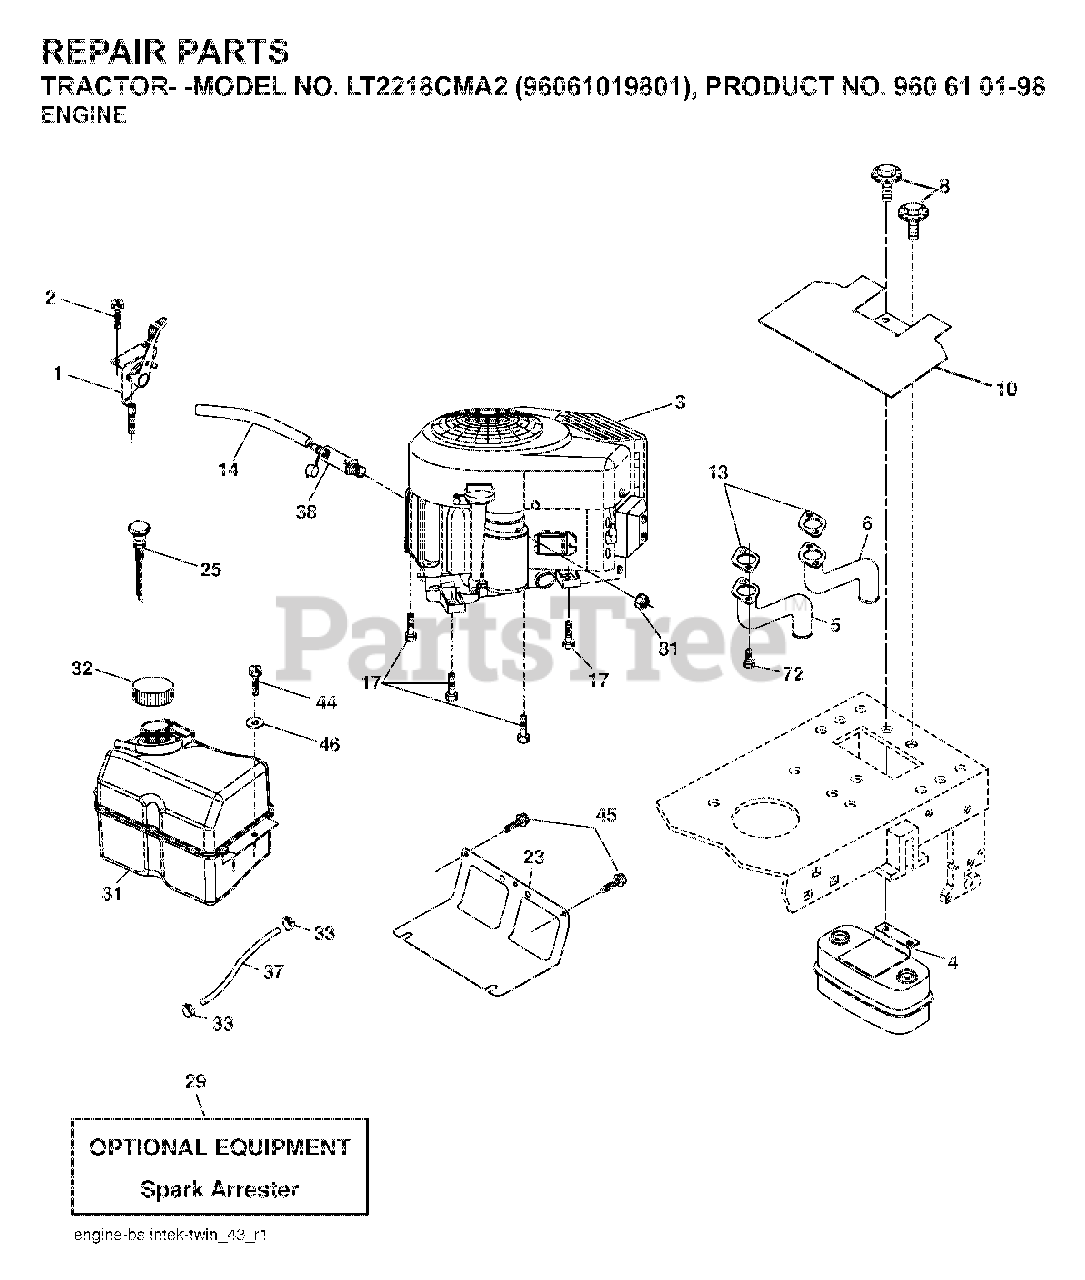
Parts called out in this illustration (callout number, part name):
1	THROTTLE CABLE
2	SCREW
4	MUFFLER.TWIN.CYL.LOW.TONE
5	EXHAUST TUBE RH
6	TUBE MANIFOLD LH
8	BOLT, 5/16-18 X 1 3/4
10	RP SHIELD HEAT MUFFLER
13	GASKET.MUFFLER
14	TUBE, DRAIN OIL ASM.
17	SCREW.3/8-16
23	SHEILD.BROWNING.DBR.GUARD
25	CONTROL CHOKE
29	ARRESTER SPARK (OPTIONAL)
31	TANK FUEL
32	FUEL CAP
33	HOSE CLAMP
37	LINE.FUEL.20
38	PLUG DRAIN OIL EASY
44	SCREW HEXWSHR 1/4-20X3/4
45	SCREW, 3/8-16X3/4
72	SCREW.SOCKET.HEAD.5/16-18
81	NUT
